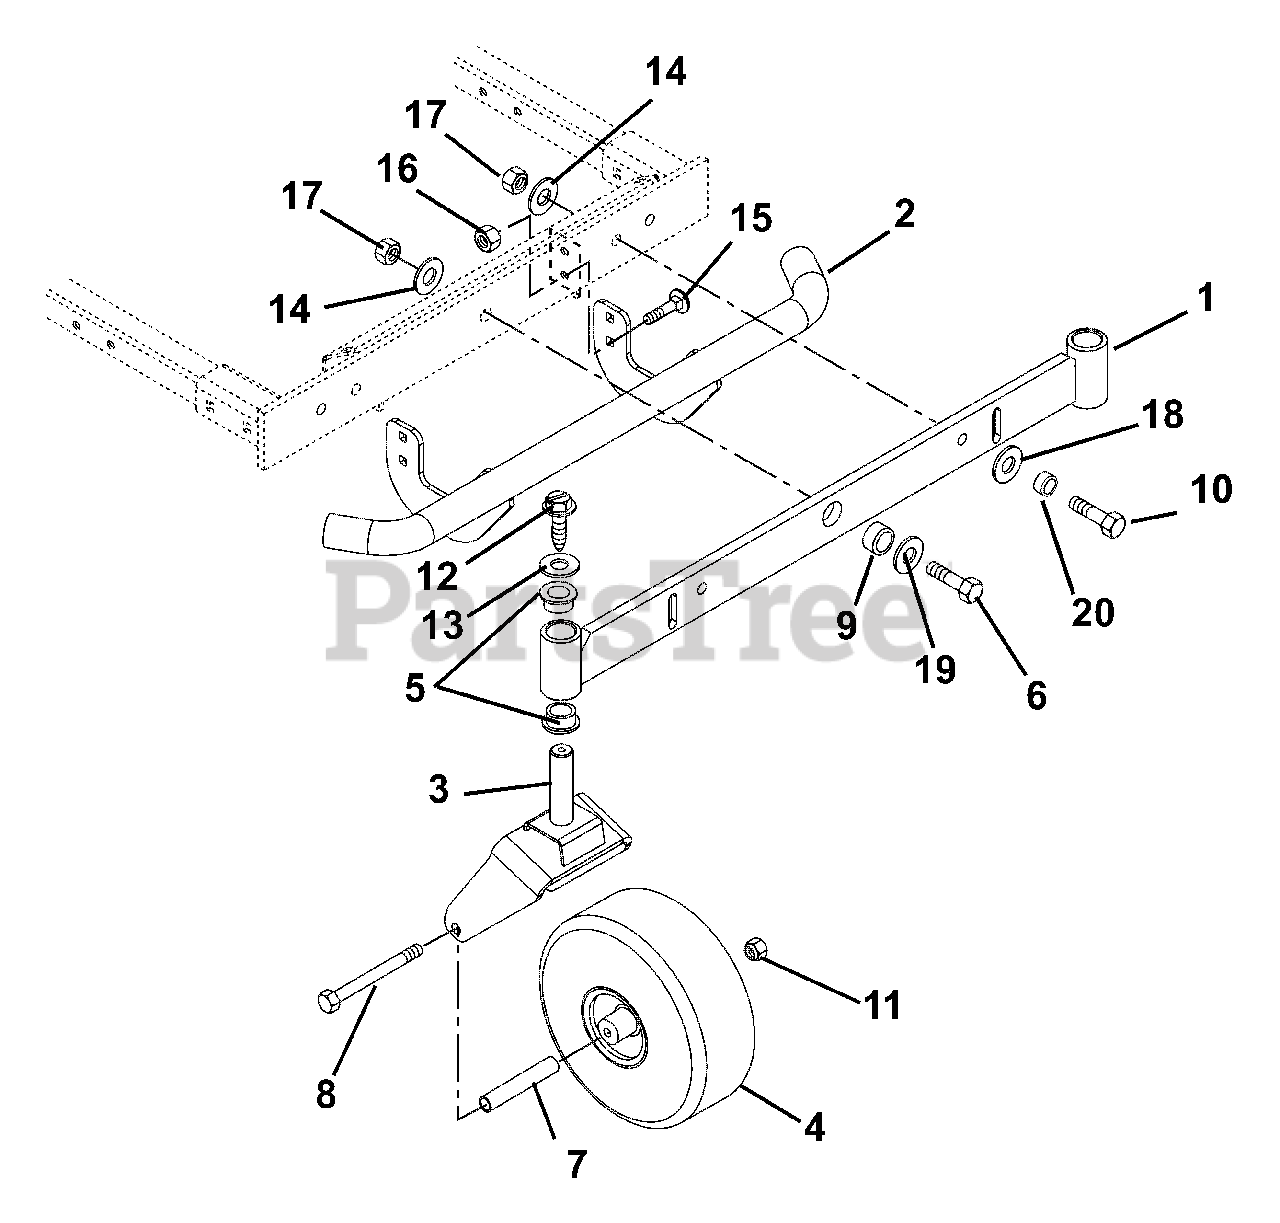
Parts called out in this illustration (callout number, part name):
1	Weldment, Front Axle
2	Bumper, Zoom
3	Fork, Caster
4	Assembly, Tire 4 x 11- 2 Ply
5	Bushing, Flange 1.00 x 1.25 x 1.50 x 1.50
6	Bolt, Hex .62-11 x 2.50 Grade 5
7	Spacer, Rolled Wheel
8	Bolt, Hex .50-13 x 6.50 Grade 5
9	Bushing, Axle Pivot
10	Bolt-Hex .62-11X2.25 Grade 8
11	Nut, Locking Top Flange .50-13
12	Screw, Tapping .38-16 x 1.25 Hex Washer Head
13	Washer-Flat-Steel .380 x 1.50 x .125
14	Washer, Flat .64 x 1.81 x .25
15	Bolt, Round Head Square Neck .38-16 x 1.00 Grade 5
16	Nut .38-16 Flange Nyloc
17	Nut, Locking Nylon .625-11
18	Washer, Flat Steel .812 x 1.50 x .135
19	Washer, Flat Steel .688 x 1.75 x .134
20	Spacer, .63 x .75 x .658 Steel
